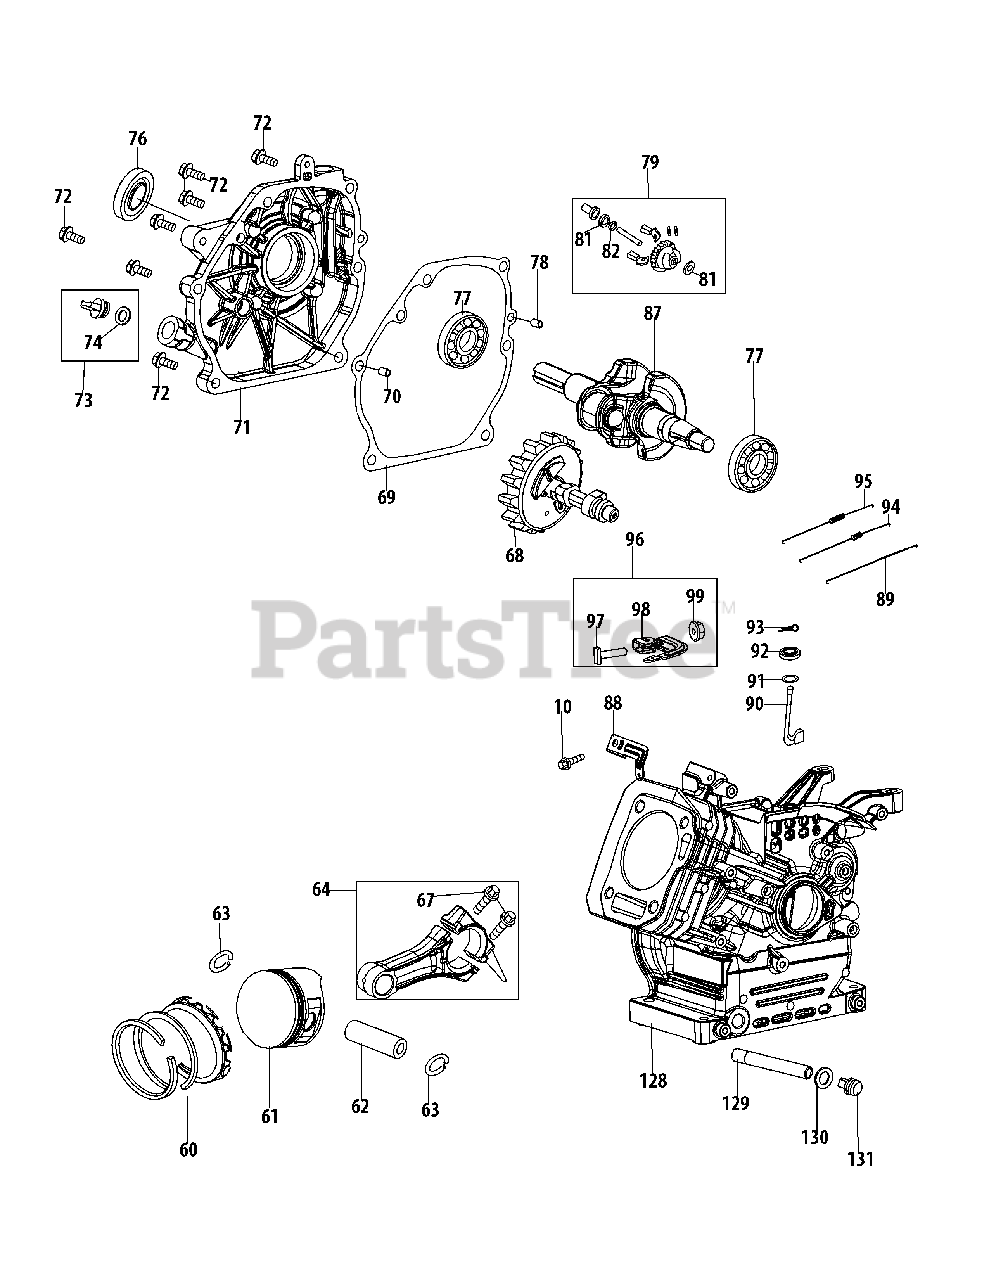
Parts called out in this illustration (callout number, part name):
10	Bolt M6×12
60	Piston Ring Set
61	Piston
64	Connecting Rod
67	Connecting Rod Bolt
68	Camshaft
69	Gasket, Crankcase Cover
70	Dowel Pin 9×14
71	Crankcase Cover
72	Bolt M8×32
73	Oil Plug
74	O-Ring 15.8×2.5
76	Oil Seal 25×41.25×6
77	Bearing Tm6205/P63
78	Dowel Pin 7×14
79	Gear Governor
81	Washer 6.2×0.6×15
82	Retaining Rings, Governor Shaft
87	Crankshaft
88	Spring Bracket
89	Rod Governor
90	Shaft,Governor Arm
91	O-Ring 5.2×1.9
92	Oil Seal 6×11×4
93	Cotter Pin
94	Idle Spring
95	Governor Spring
96	Governor Lever
97	Bolt M6×21
98	Governor Lever
99	Flange Nut M6
128	Crankcase
129	Oil Drain Pipe
130	Washer 10×1.5×16
131	Washer,Drain Bolt(M10×1.25×15)
